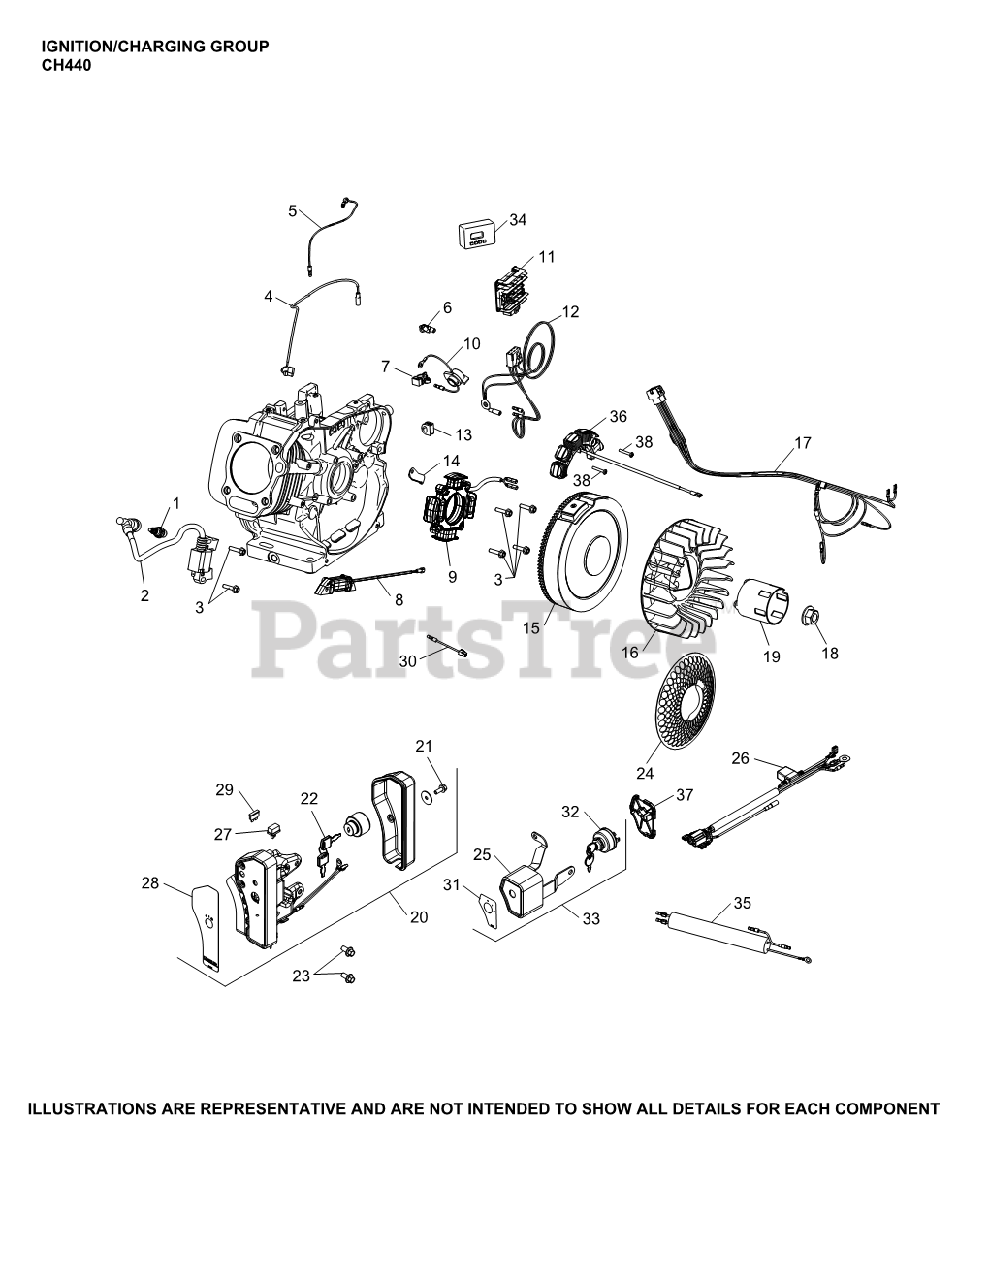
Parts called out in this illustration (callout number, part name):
1	SPARK PLUG
2	MODULE, IGNITION
3	SCREW, M6 X 25 USE 25 086 436-S
4	LEAD, GROUND TO KILL
14	BRACKET, STATOR WIRE
15	FLYWHEEL ASSY ELECTRIC START (CH440)
16	FAN, FLYWHEEL
18	NUT, FLYWHEEL
19	CUP, STARTER DRIVE
21	SCREW, HEX FLANGE (M6)-USE 25 086 433-S
36	STATOR ASSEMBLY, 1 AMP
38	SCREW, STATOR MOUNTING (CKY)
